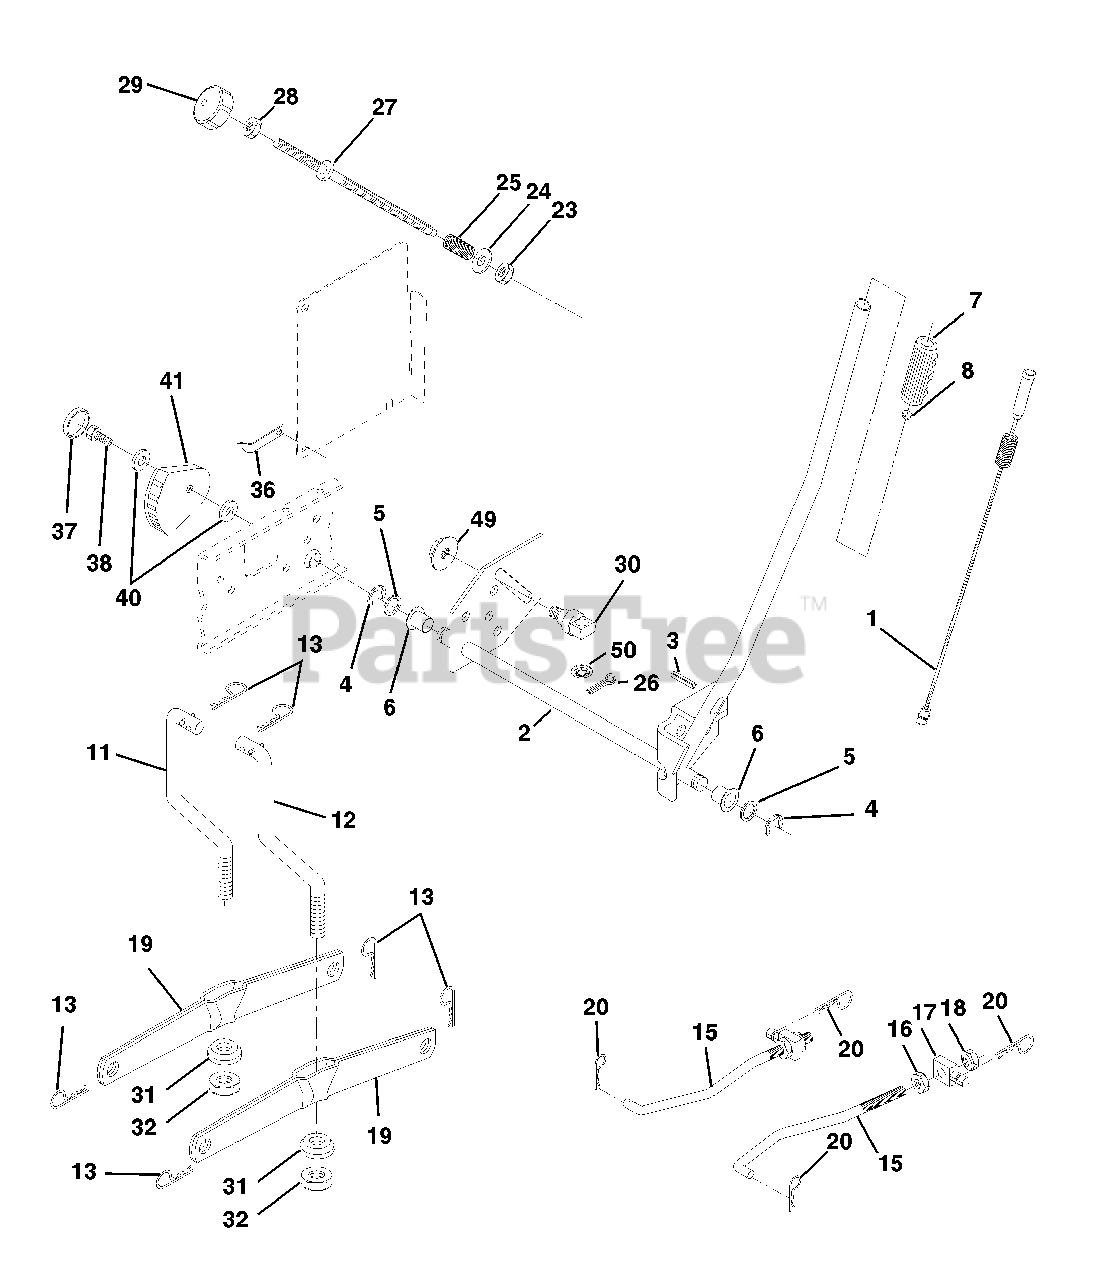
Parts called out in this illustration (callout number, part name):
1	Wire Asm Inner W/plunger
2	Shaft Asm Lift RH w/Inf
3	Pin Groove 1 500 Zinc
4	E Ring #5133-62
5	Washer 21/32 X 1 X 21 Ga
6	Bearing Nylon Blk 629 Id
7	Grip Handle Fluted Blk
8	Button Plunger Black
11	Link Lift LH Fixed Length
12	Link Lift RH Fixed Length
13	Retainer Spring
15	Link Front
16	Nut Jam Hex 1/2-13 Unc
17	Trunnion Blk Zinc
18	Nut Crownlock 1/2-13unc
19	Arm Suspension Rear
20	Retainer Spring
23	Nut Special
24	Washer 13/32 X 5/8 X 16 Ga
25	Spring 2-1/8"
26	Pin Cotter 3/32 X 1/2
27	Rod Adj Lift Zinc 7.49 Wrk Lg
28	Nut Hex Jam 3/8-16 Unc
29	Knob Inf 3/8-16 Unc Blk W/sym
30	Trunnion Infin Height
31	Bearing Pvt Lift Spherical
32	Nut Crownlock 3/8 - 24
36	Pointer Height Indicator
37	Plug Hole Blk 1.485/1.515 Dia.
38	Screw Thdrol 5/16-18 x 3/4
40	Washer 11/32 x 1-1/2 10 Ga.
41	Indicator Height STLT
49	Nut Hex Flange Lock
50	Nut Phos & Oil
